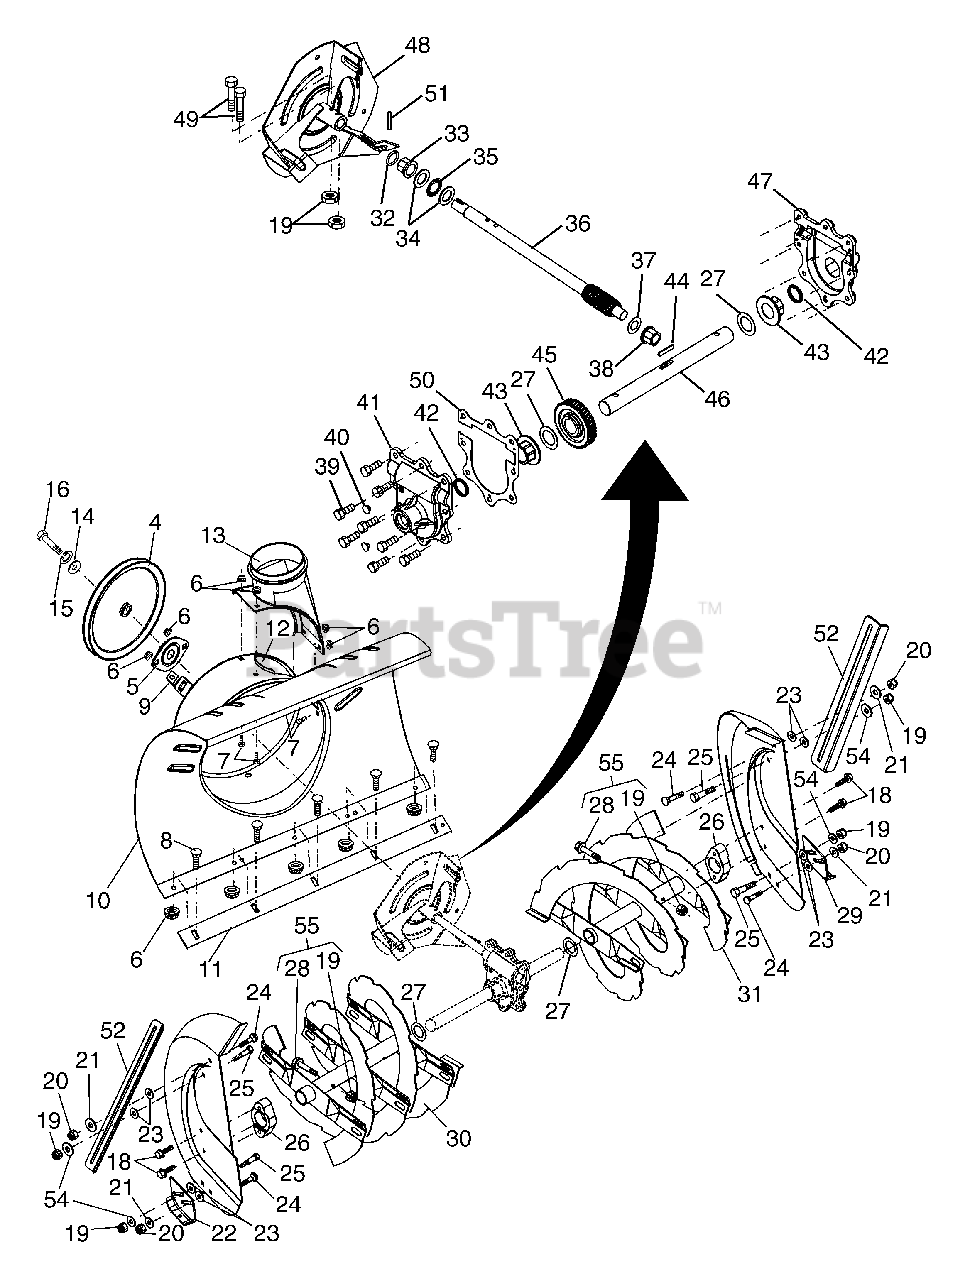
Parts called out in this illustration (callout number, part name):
4	Pulley, Impeller
5	Bearing Assembly, Flange
6	Nut, Hex Flange 5/16-18
7	Bolt, Flat Head, Carriage 5/16-18 x 5/8
8	Bolt, Carriage 5/16-18 x 5/8
9	Nut, Cage 3/8-16
10	Housing, Auger
11	Bar, Scraper
12	Bracket, Corner Discharge
13	Base, Discharge Chute
14	Washer, Flat
15	Washer, Lock 5/16
16	Screw, Hex Head 5/16-18 x 3/4
18	Screw, Hex Head 5/16 x 1
19	Nut, Hex Lock 1/4-20
20	Nut, Hex Lock 5/16-18
21	Washer, Flat 5/16
22	Skid Plate, RH
23	Washer, Nylon, Friction
24	Bolt, Carriage 5/16-18 x 3/4
25	Bolt, Shoulder 1/4-20
26	Bearing, Auger
27	Washer, Thrust, 1"
28	Bolt, Shear
29	Skid Plate, LH
30	Auger Assembly, RH
31	Auger Assembly, LH
32	O-Ring
33	Bushing, Flange 3/4
34	Washer, Thrust 3/4
35	Bearing, Thrust 3/4
36	Shaft, Impeller
37	Washer, Thrust 5/8
38	Bushing, Flange 5/8
39	Screw, Hex Head 5/16-18 x 3/4
40	Plug, Case
41	Housing, Gearbox, RH
43	Bushing, Flange, 1"
44	Key, Square 1/4 x 1/4 x 7/8
45	Gear, Worm
46	Shaft, Auger
47	Housing, Gearbox, LH
48	Impeller Assembly
49	Screw, Hex Head 1/4-20 x 1-5/8
50	Gasket, Gearbox
51	Pin, Roll 3/16 x 1-1/8
52	Bar, Drift Cutter
54	Washer, Flat 1/4
55	Kit, Shear
